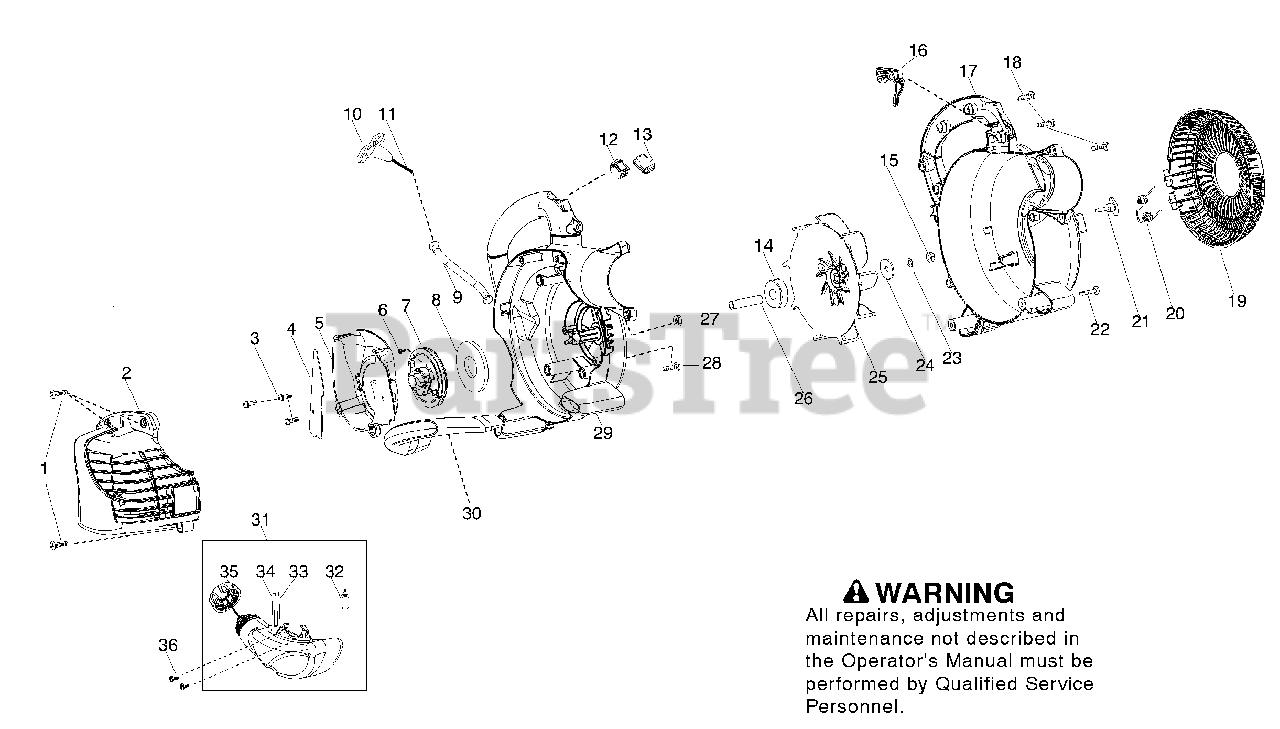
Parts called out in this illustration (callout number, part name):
2	Assy - Engine Cover
4	Shield - Baffle
7	Kit - Starter Pulley
8	Spring - Starter
9	Tube - Starter Rope
10	Handle - starter
12	Kit - Switch (momentary)
13	Protector - Switch
16	Trigger - Throttle
17	Assy - Scroll LH
20	Spring - Vac Door
21	Knob - Blower
22	Screw - Handle Vac
23	Washer - Lock
24	Washer - Impeller
25	Assy-Impeller
26	Spacer - Flywheel
29	Assy-Scroll Assy. RH
31	Assy - Fuel Tank
32	Assy - Fuel Pickup
33	Kit - Fuel Line (carb/purge)
34	Kit - Fuel Line (tank/purge)
35	Assy - Fuel Cap w/retainer
36	Screw - Fuel Tank Retainer
